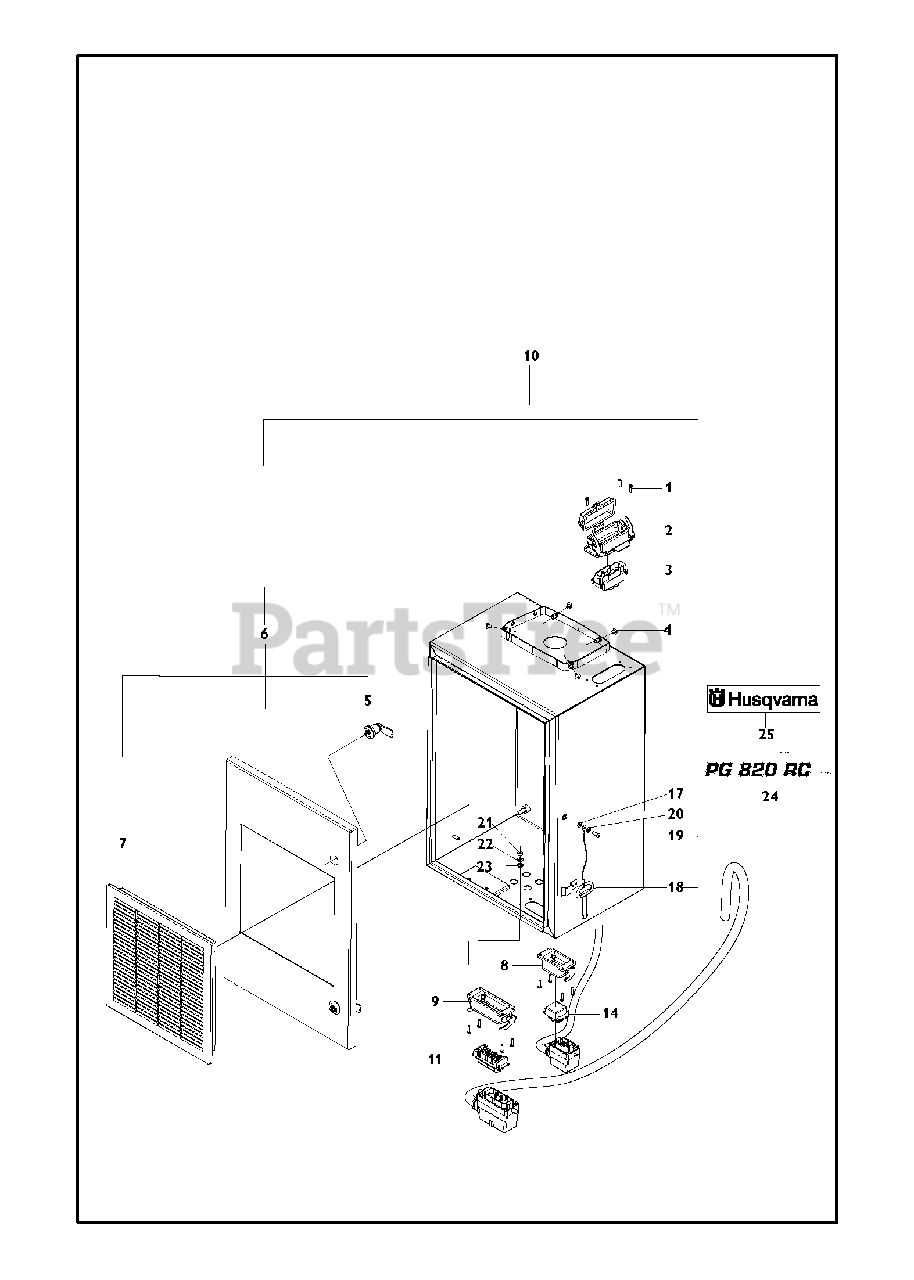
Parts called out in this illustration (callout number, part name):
1	SCREW CRPANM
17	WASHERWASHER
19	SCREW IHSCMSCREW IHPANM
20	WASHERWASHER
21	HEXAGON LOCKING NUTLOCK NUT
22	WASHERWASHER
23	LOCKWASHERLOCK WASHER
